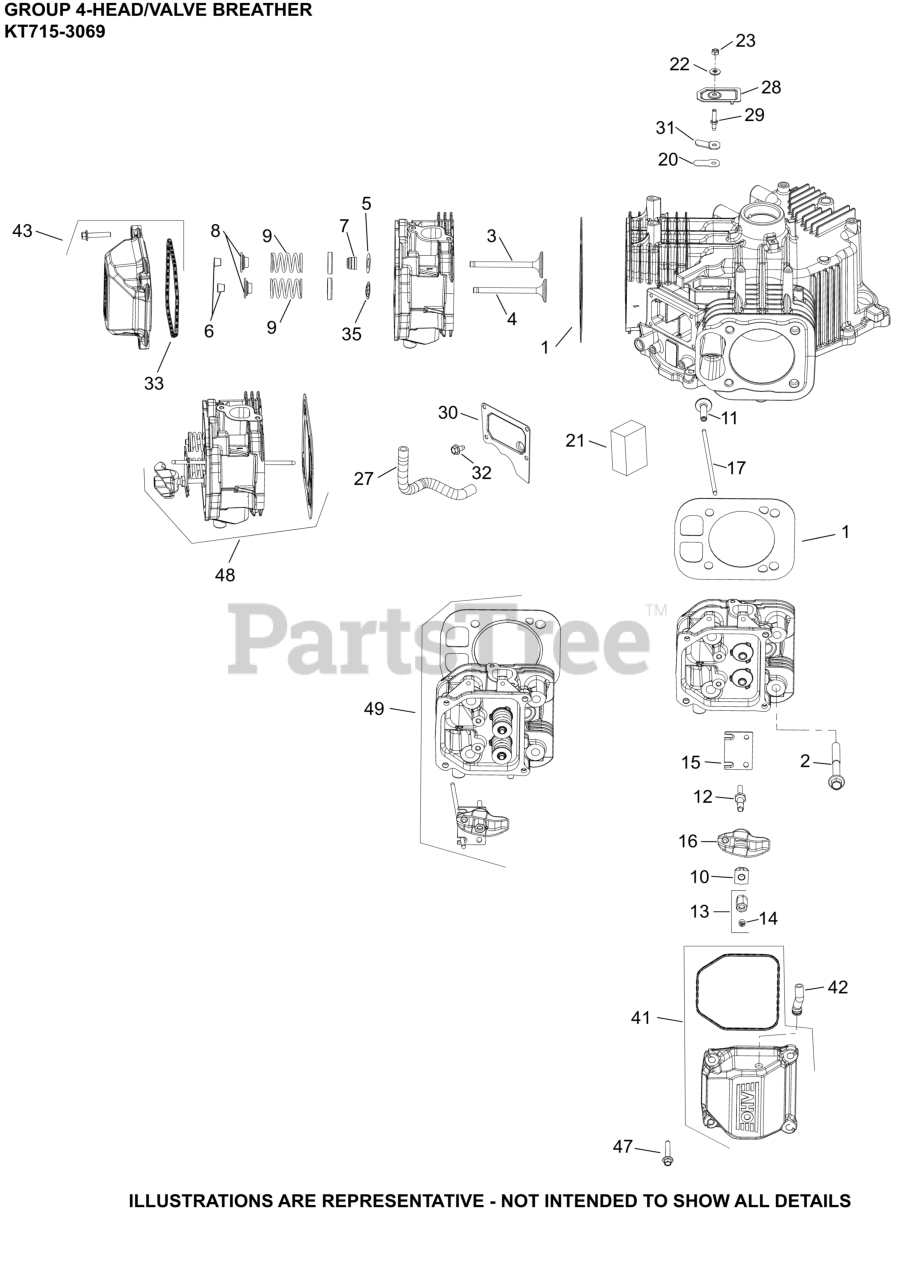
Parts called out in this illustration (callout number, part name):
1	KIT, CYLINDER HEAD GASKET
2	SCREW, HEX FLANGE M10 X 1.5-6g X 90mm
3	VALVE, INTAKE
3	VALVE, INTAKE (.25) - (#2401702S)
4	VALVE, EXHAUST
4	VALVE, EXHAUST (.25)
5	SPACER (.010")
6	KIT, RETAINER
7	SEAL, VALVE BAND
8	CAP, VALVE SPRING
9	SPRING VALVE
10	PIVOT, ROCKER ARM
12	STUD, ROCKER
13	HEX NUT ASSEMBLY
14	SCREW, SET
15	PLATE, GUIDE
16	ARM, ROCKER
17	ROD, PUSH
20	REED, BREATHER
21	FILTER, BREATHER
22	WASHER, SEALING
23	NUT, LOCK M5X.8
27	HOSE, BREATHER
28	COVER, BREATHER REED
30	COVER, BREATHER MEDIA
31	RETAINER, REED
32	SCREW, THREAD FORMING
33	O-RING (YELLOW), VALVE CO
35	RETAINER, VALVE GUIDE (KM)
41	KIT,BREATHER VALVE COVER (PLASTIC)
42	HOSE, FP-USE 32 326 07-S(PLASTIC COVERS)
43	KIT, VALVE COVER-PLAIN (PLASTIC)
47	SCREW, HEX FLANGE (M6 X 31.625 DOG PT)
48	KIT, #1 CYLINDER HEAD
49	KIT, #2 CYLINDER HEAD
